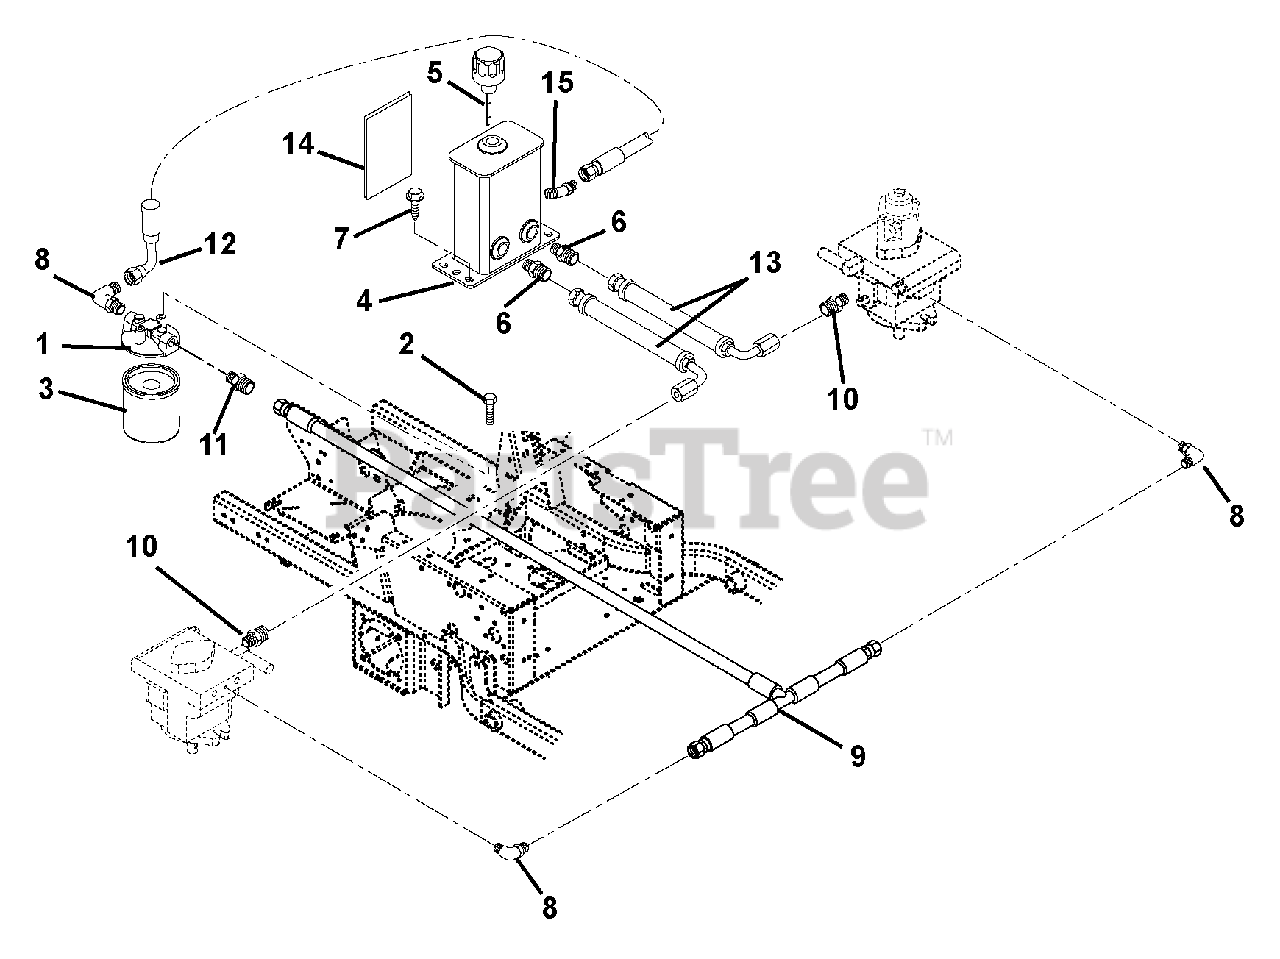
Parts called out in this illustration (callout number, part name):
1	HEAD, FILTER
2	BLT-HEX .25-20X.50 GR5 EPOXY
3	ELEMENT, FILTER BE-40-0
4	WMT, HYDRAULIC TANK
5	BREATHER, DIPSTICK
6	FTG, HYD STR M8O-M4F
7	@SCR-TAP .38-16X.75 HWH TR YWZ
8	FITTING, HYD (6 C5OLO)
9	HOSE, TEE ASSM .38
10	FITTING, HYD (4-6 F5OLO)
11	FITTING, HYD (6 F5OLO)
12	HOSE, HYD .38-9-0K F6F0-F6F9
13	HOSE, HYD .25-3-0K F4F0-F4F9
14	SHEILD, HEAT 5.50X4.50
15	FTG, HYD 45DEG M6F-M8O
